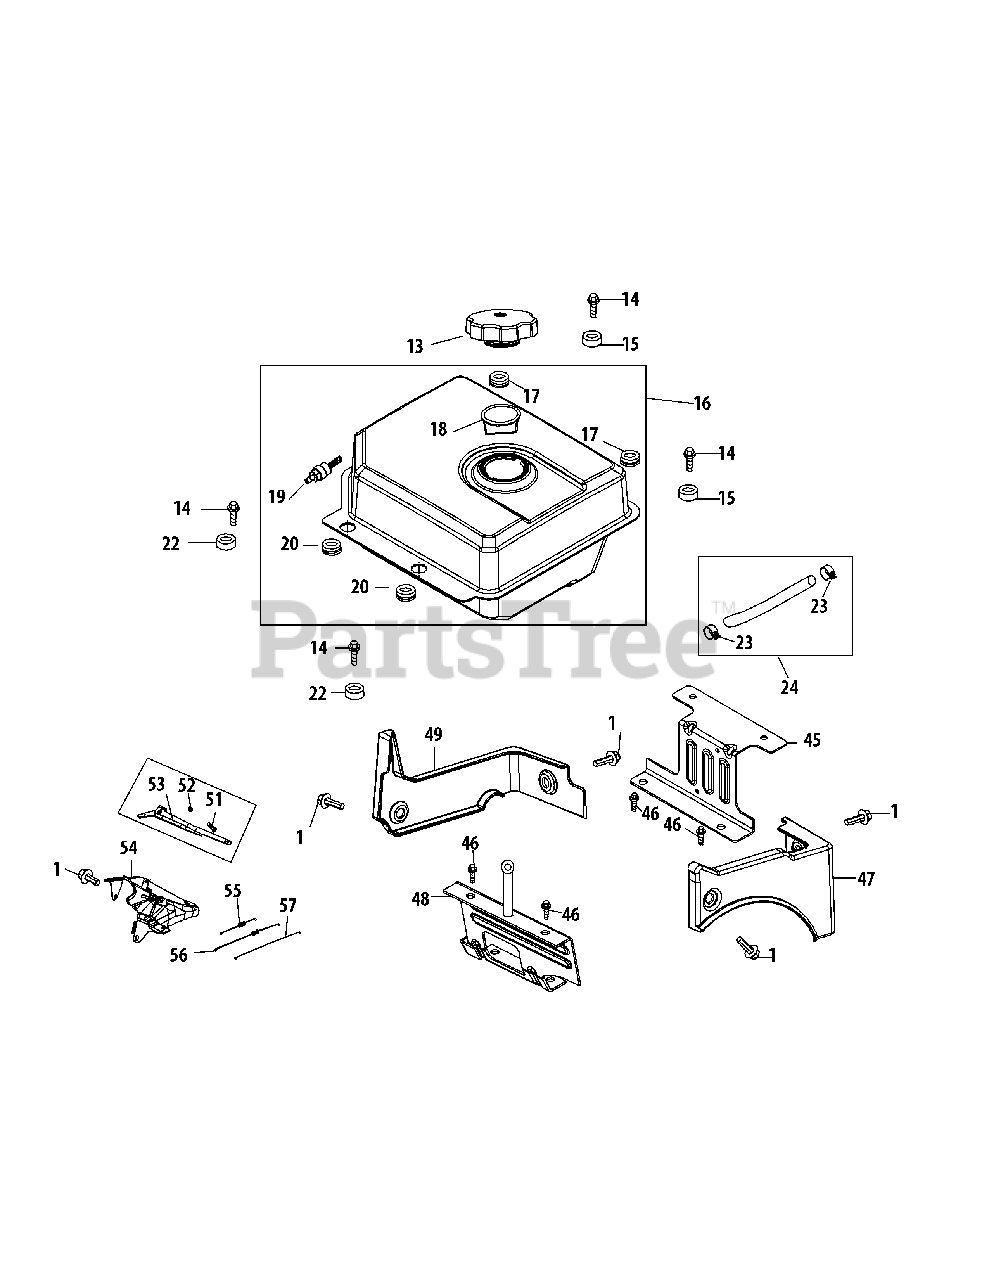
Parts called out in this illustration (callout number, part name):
1	BOLT M6×12
13	FUEL CAP ASSEMBLY
14	BOLT M8×20
15	BUSH, GAS TANK
16	FUEL TANK ASSEMBLY
17	VIBRATION PAD
18	FUEL LEVEL INDICATOR
19	DRAIN PIPE
20	VIBRATION PAD
22	BUSH, GAS TANK
23	FUEL HOSE CLAMP
24	FUEL HOSE
45	REAR MAINTING BRACKET ASSY.
46	BOLT M8×14
47	RIGHT TRIM PLATE
48	GAS TANK SUPPORT BRACKET
49	LEFT TRIM PLATE
51	GOVERNOR ARM BOLT
52	NUT M6
53	GOVERNOR ARM
54	THROTTLE BRACKET
55	GOVERNOR SPRING
56	THROTTLE LINKAGE SPRING
57	THROTTLE LINKAGE
